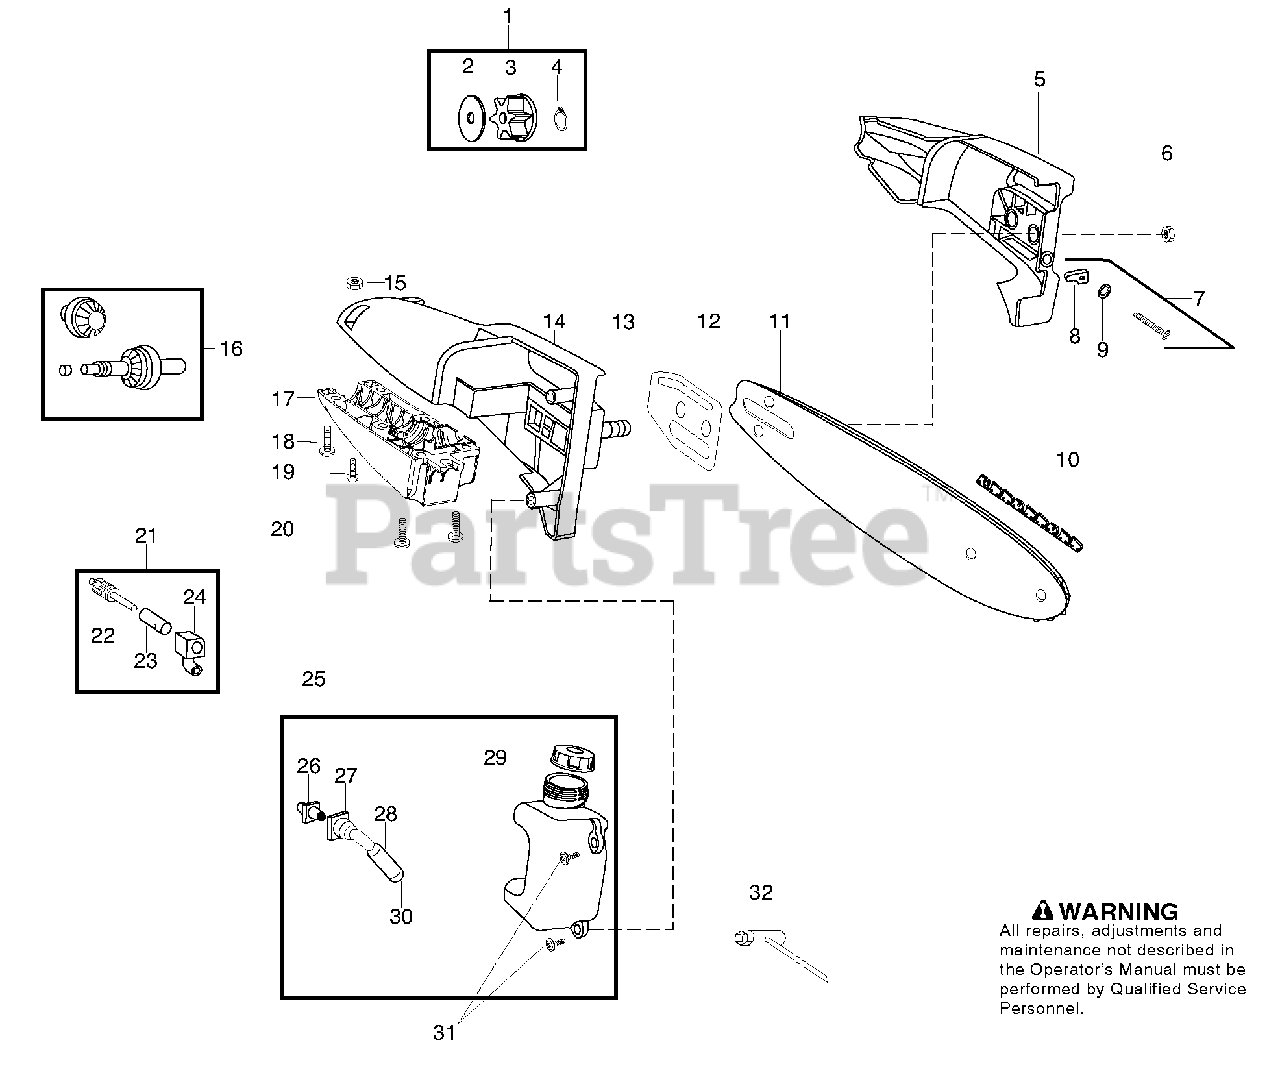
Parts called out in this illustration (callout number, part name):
1	Kit - Sprocket Assy.
3	Sprocket
4	Retainer - Sprocket
5	Assy - Bar Clamp
6	Nut - Bar Mounting
7	Kit - Bar Adjust
8	Pin - Bar Adjust
9	Retainer - Bar Adjust
10	Chain - 8"
11	Bar - 8"
12	Plate - Bar Pad
13	Bolt - Bar
14	Housing - Upper
16	Kit - Gear Assy.
17	Housing - Lower
18	Screw (10-24)
19	Screw - Alignment (10-14 x 1/2")
20	Screw (10-14 x 13/16")
21	Kit - Oil Assy
22	Assy. - Gear Plunger
24	Assy- Oil Block
25	Assy - Oil Tank
26	Fitting - Oil Line
27	Intake - Oil Line
28	Filter - Oil
29	Cap - Oil
30	Plug - Oil Filter
31	Screw (10-24 x 7/8")
32	Wrench - Bar
